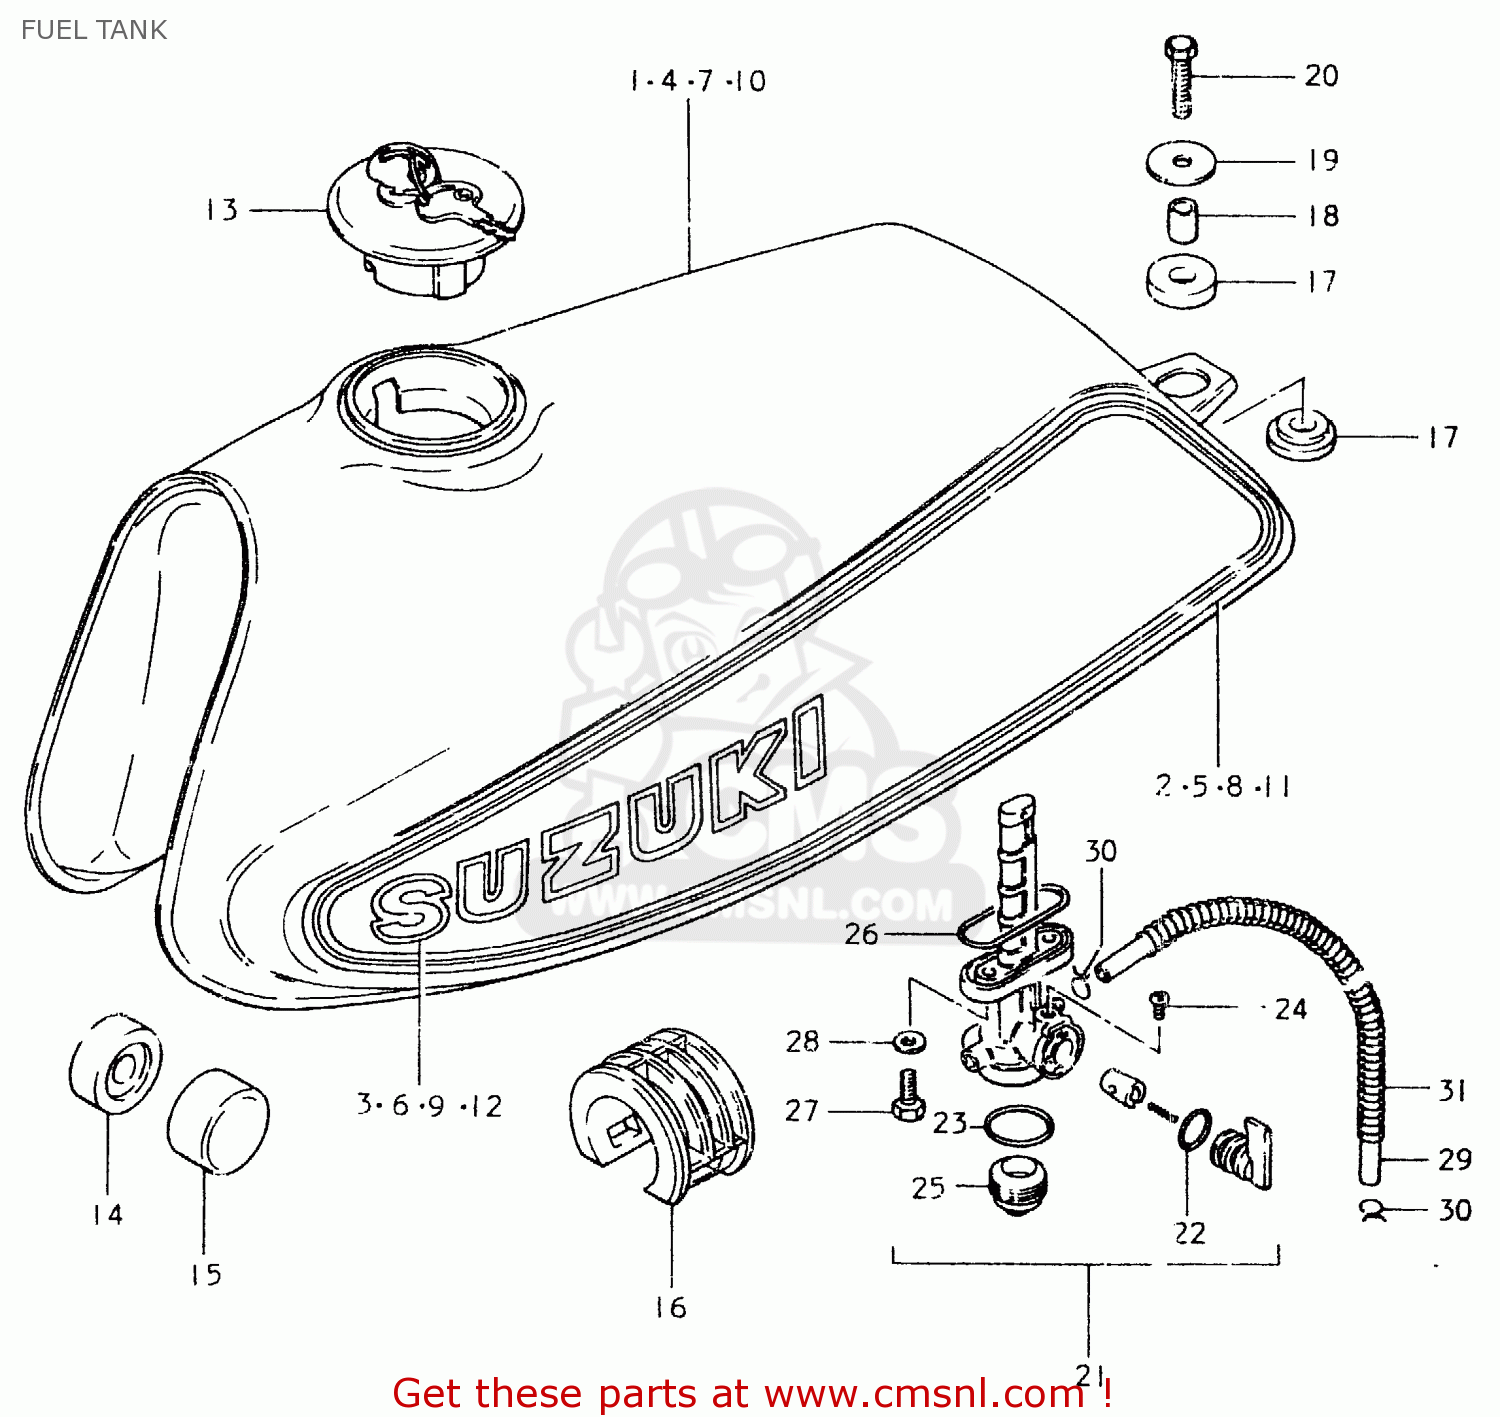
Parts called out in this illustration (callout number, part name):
1	TANK ASSEMBLY,FUEL
2	TAPE SET,FUEL TANK
3	EMBLEM,FUEL TANK(WHITE)
4	TANK, FUEL (BLUE)
5	TAPE SET
6	EMBLEM,FUEL TANK(WHITE)
7	TANK, FUEL (SILVER)
8	TAPE SET
9	EMBLEM
10	TANK, FUEL (BROWN)
11	TAPE SET,FUEL TANK
12	EMBLEM,FUEL TANK(WHITE)
13	CAP SET,FUEL TANK
14	CUSHION
15	CUSHION
16	CUSHION,FUEL TANK
17	BUSH(12X15X20)
18	SPACER (8X12X15)
19	WASHER (8.5X29X1.6)
20	BOLT
21	COCK ASSEMBLY,FUEL
22	O-RING
23	GASKET,FILTER (NAS)
24	SCREW,FUEL COCK LEVER
25	CUP,STRAINER
26	O RING,FUEL COCK
27	BOLT(6X20)
28	GASKET
29	HOSE
30	CLIP
31	SPRING
